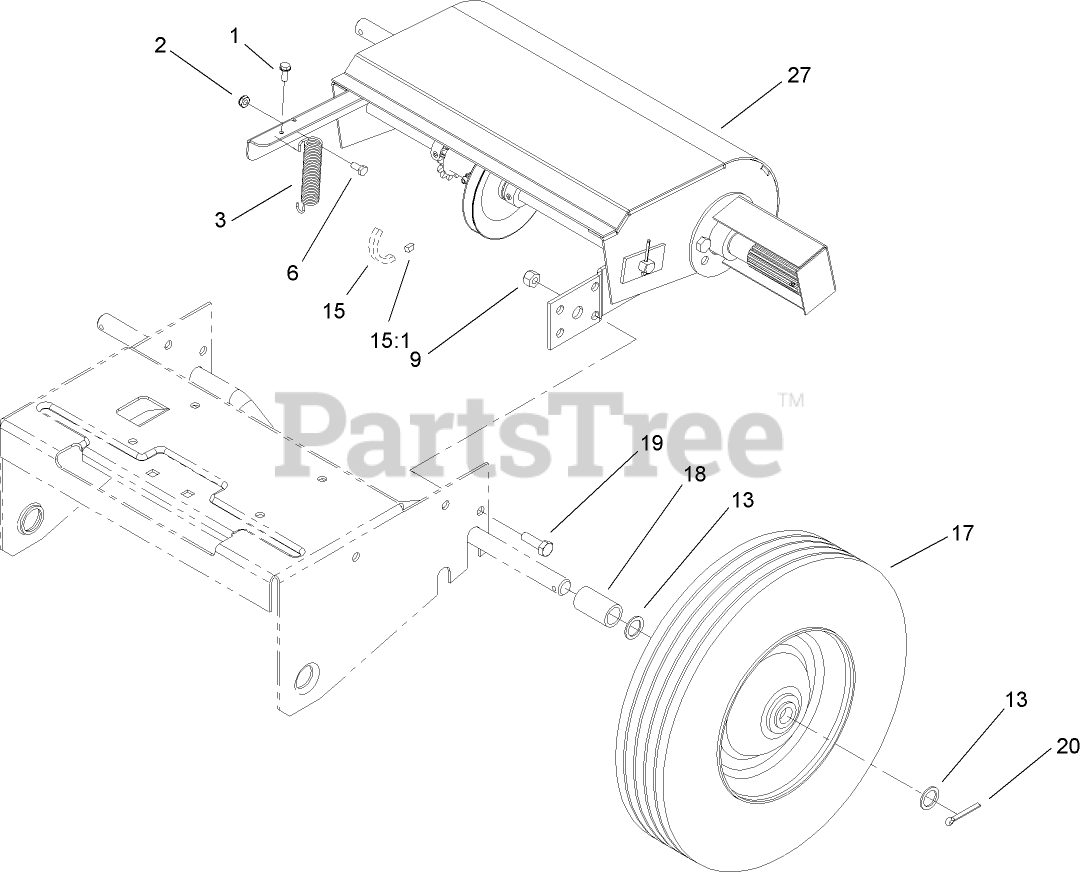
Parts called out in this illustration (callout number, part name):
1	SCREW-HH
2	NUT-LOCK, NI
3	SPRING-TRACTION
6	SCREW-HH
9	NUT-LOCK, NI
13	WASHER
15	CHAIN-ROLLER, REEL DRIVE
15:1	LINK-CONNECTING, NO. 35
17	WHEEL
18	SPACER-AXLE
19	SCREW-HH
20	PIN-COTTER
27	Traction ASM
